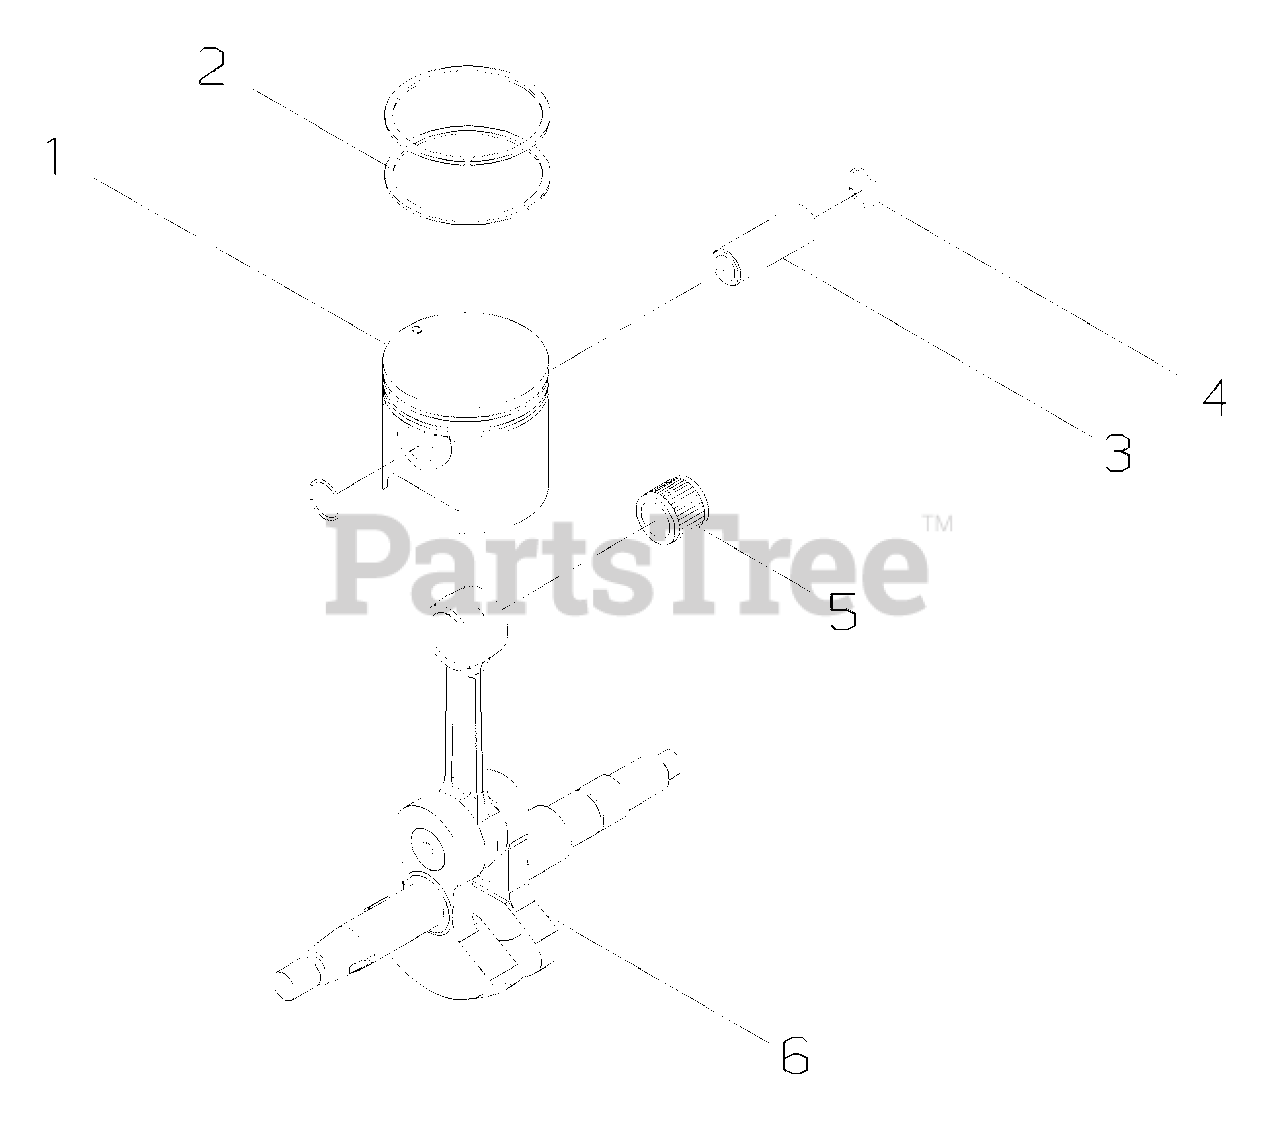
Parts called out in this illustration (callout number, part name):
1	PISTON
2	RING, PISTON
3	PIN, PISTON
4	RING, RETAINING
5	BEARING, NEEDLE
6	CRANKSHAFT ASSY
